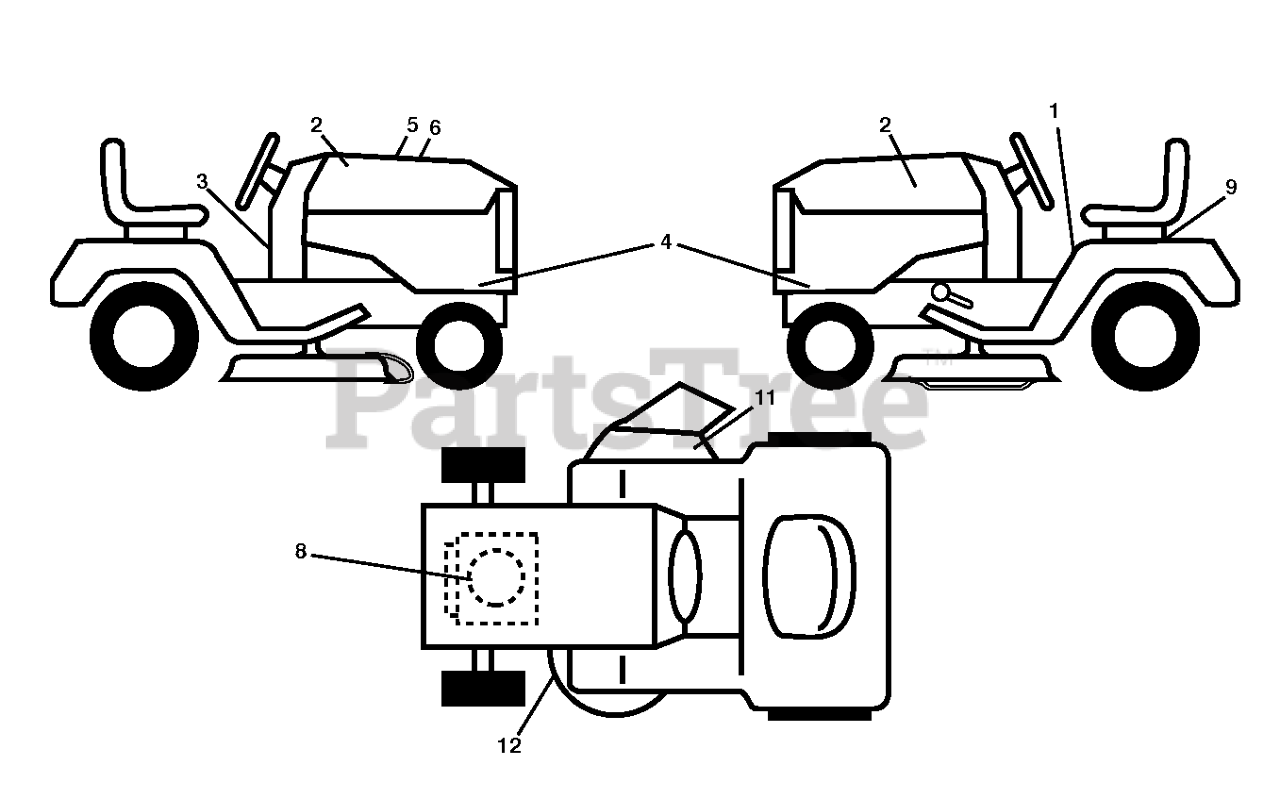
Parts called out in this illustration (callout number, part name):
1	DECAL.FENDER.WARNING.ENG
2	DECAL.HOOD.LOGO.ORANGE.HUSQVAR
3	DECAL, WARNING SPARK ARRESTOR
4	DECAL PANEL SIDE
5	DECAL.WARNING.CUST.RESP.E85.
6	Decal, Replacement
8	DECAL.ENG.BS.20HPXRD.SL.278416
9	DECAL BTRY SYMBOLS
11	DECAL.WARN.KEEP.HAND.AWAY
12	DECAL V BELT SCHEMATIC
